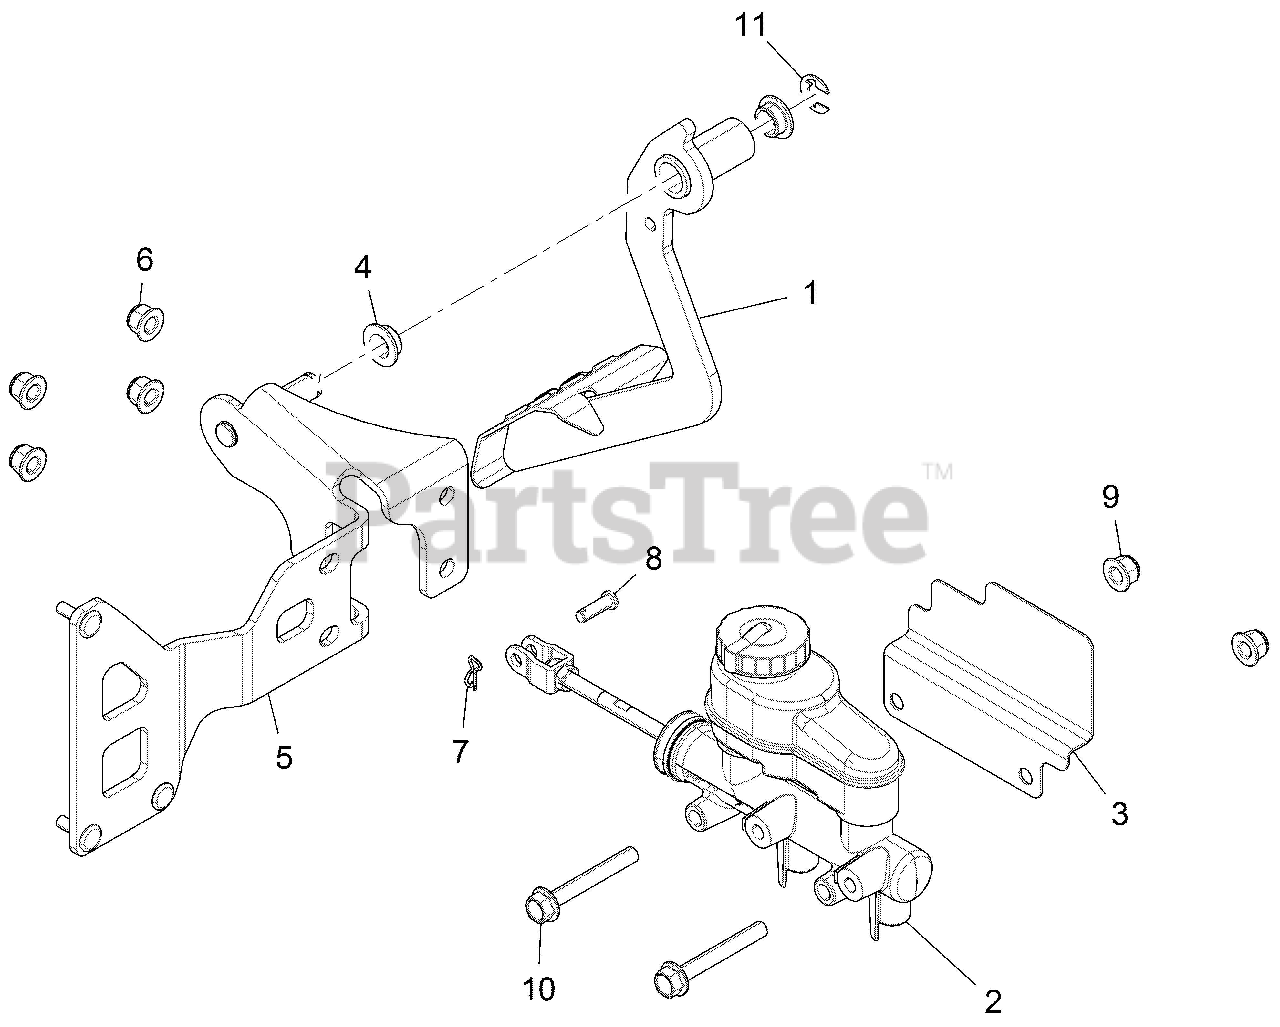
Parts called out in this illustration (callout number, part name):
1	PEDAL, BRAKE, MATTE BLACK
2	ASM., MASTER CYLINDER
3	SHIELD-MASTER CYL
4	BUSHING-PEDAL PIVOT
5	MOUNT, PEDAL, BLACK
6	NUT-M8X1.25,FLG,NYLOC-OLIVE D
7	PIN-CLIP,14MM
8	PIN-CLEVIS, 1/4 X 3/4 -Y
9	NUT-M8X1.25,FLG,NYLOC-OLIVE D
10	SCREW
